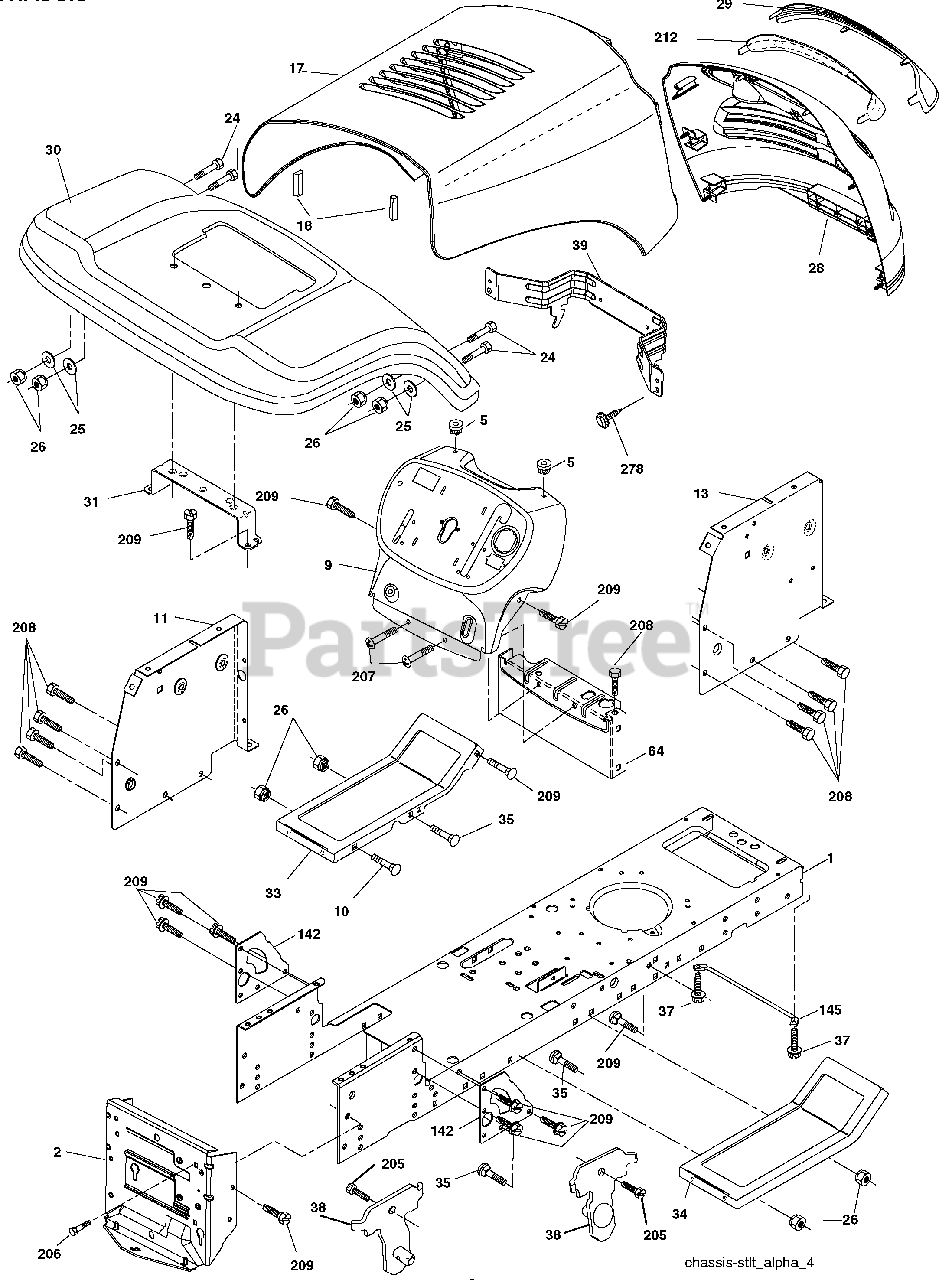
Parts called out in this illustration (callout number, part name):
1	Chassis
2	Drawbar, Stretch
5	Bumper, Hood/Dash
9	Dash
10	Bolt, Carriage 3/8-16 x 1
11	Panel Dash LH
13	Panel Slkscr Dash RH
17	Hood
18	Bumper Hood
24	Bolt Fin Hex 3/8-16 unc x 1 Gr. 5
25	Washer 13/32 x 13/16 x 12 Ga.
26	Nut Lock Hex w/Ins 3/8-16 unc
28	Grille/Lens Asm
29	Lens Grille Basic Bar
30	Fender
31	Bracket Fender Repl 109873X
33	Footrest Pnt LH
34	Footrest Pnt RH
35	Bolt Rdhd Sht Sqnk 3/8-16 x 3/4
37	Screw Thdrol 5/16-18 x 1/2 TYT
38	Bracket Asm. Pivot Mower
39	Bracket Pivot
64	Dash Lower
142	Plate Reinforcement
145	Rod Pivot Hood
205	Screw Thdrol 3/8-16 x 1/2
206	Bolt Shoulder 5/16-18
207	Screw Thdrol 5/16-18 x 1/2
208	Screw Thdrol 3/8-16 x 1/2
209	Screw Hex Wsh Thdrol 3/8-16
212	Insert Lens Reflect
278	Screw 10 x 3/4 Single Lead-Hex
278	Plug Button Blk 359 Dia Choke
278	Plug Dome Plastic
